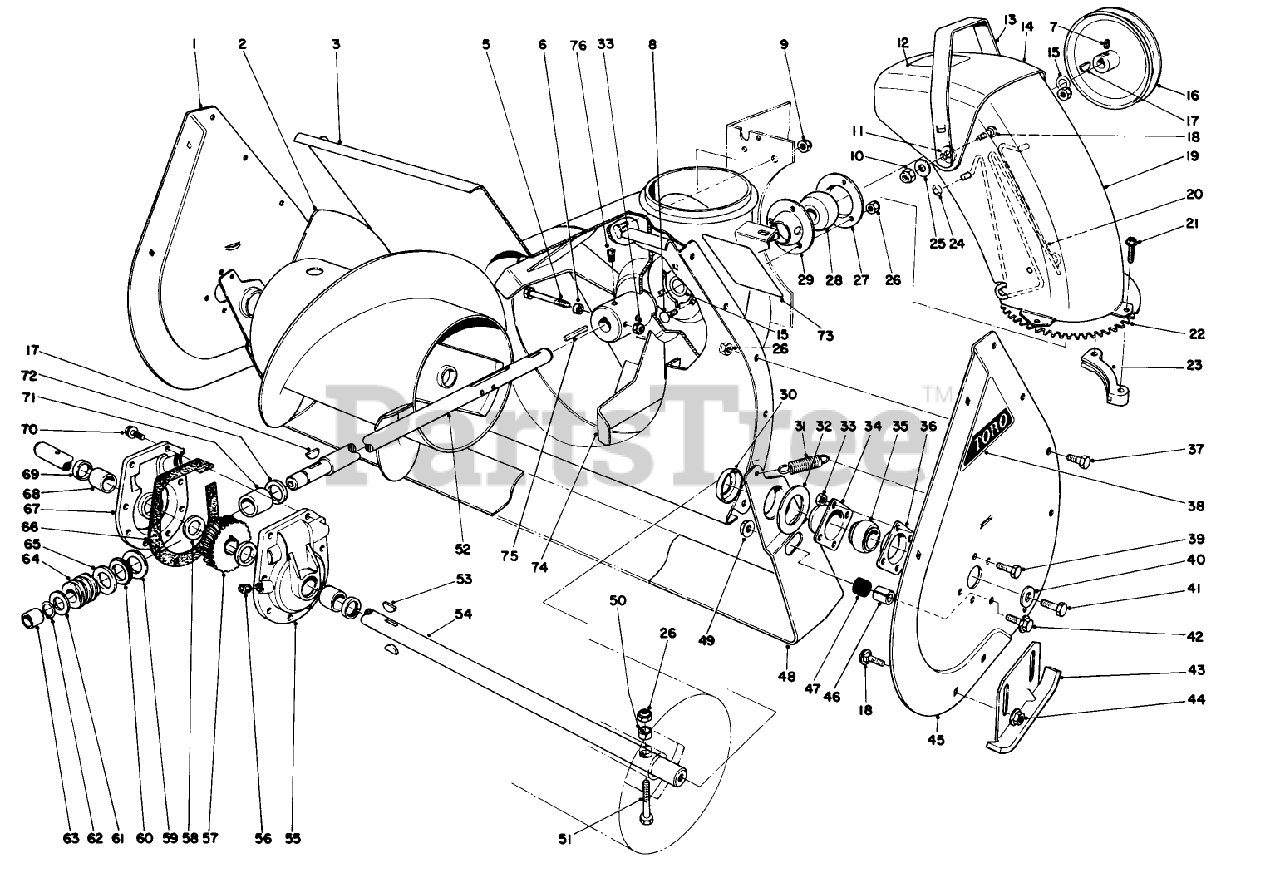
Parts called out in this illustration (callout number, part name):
3	AUGER HSG ASM
5	SCREW-HHF
6	SPACER
7	SCREW-SET, SQH
8	BOLT-CARR
9	NUT-LOCK, NI
10	NUT-LOCK, SIDE
11	WASHER-RUBBER
13	DEFLECTOR HANDLE *B
15	WASHER
16	IMPELLER PULLEY
17	KEY-WOODRUFF
18	SCREW-CARR
20	CHUTE WIRE
21	SPECIAL SCREW
23	CHUTE RETAINER
24	NUT-PUSH
25	WASHER-BELLEVILLE
26	NUT-LOCK, NI
27	Bearing-Flange Rear
28	BEARING-BALL
29	Bearing-Flange, Front
31	SPRING-TENSION
32	SCRAPER BLADE SPACER
33	NUT-LOCK, NI
34	BEARING-FLANGE, FRONT
35	BEARING
36	BEARING-FLANGE, REAR
37	SCREW-HHF
39	SCREW-HH
40	WASHER
41	SCREW-HH
42	SCREW-HHF
44	NUT-HHF, WHIZ
45	LH AUGER SIDE PLT *R
47	SCRAPER STOP CUSHION
49	NUT-HF
50	SPACER-HUB, AUGER
53	KEY-WOODRUFF
56	PLUG-PIPE, SQH
57	GEAR-WORM, 27T
58	WASHER-THRUST
59	WASHER-THRUST
60	BEARING-THRUST
61	WASHER-THRUST
62	RING-SNAP
63	BUSHING
65	THRUST-WASHER
66	GASKET-CASE, GEAR
68	BUSHING
69	SEAL-OIL
70	SCREW-TAPTITE
71	BUSHING-SPECIAL
72	RING-QUAD
76	SCREW-SET, SQH
